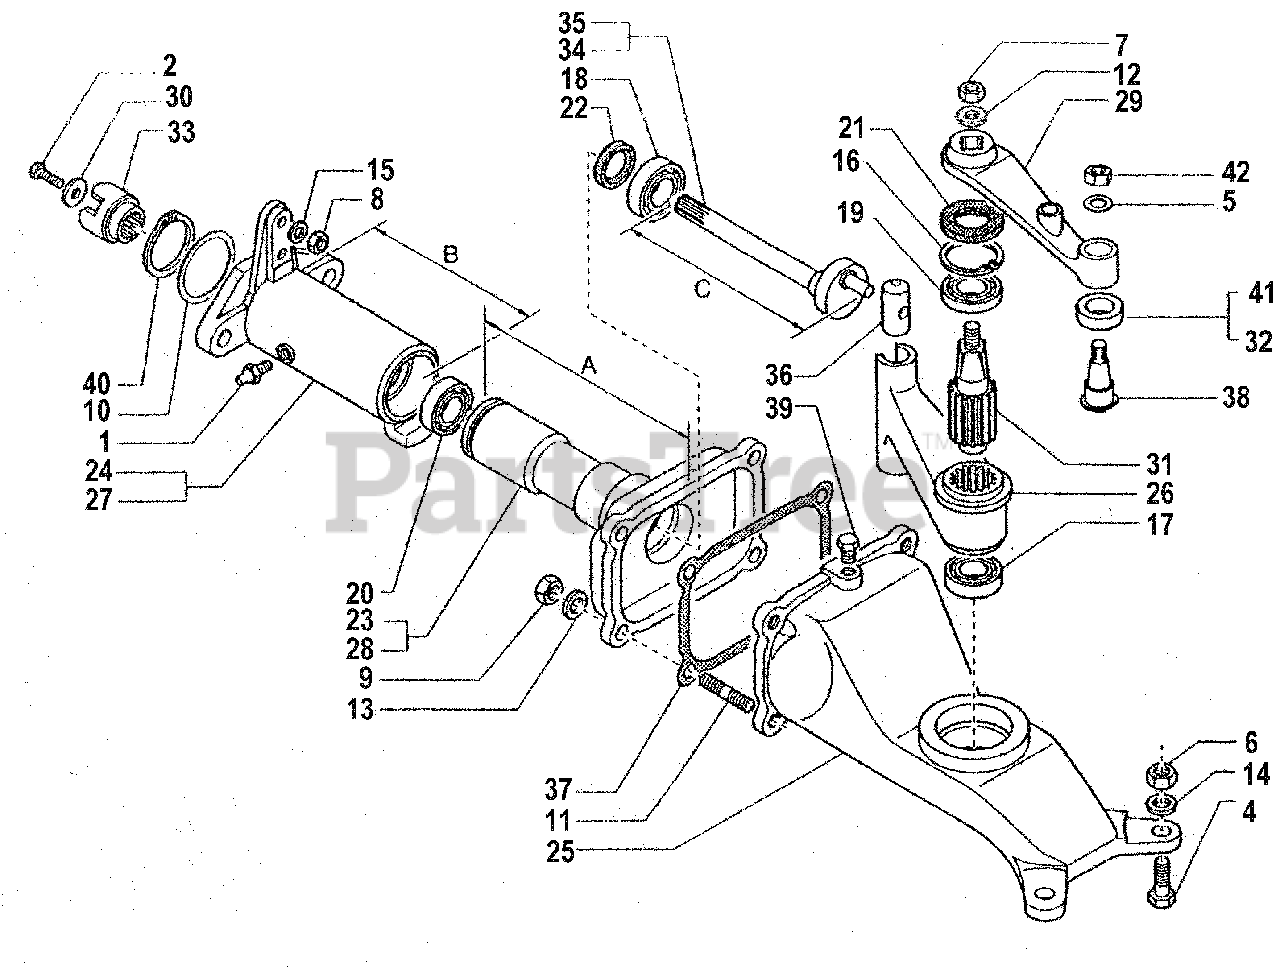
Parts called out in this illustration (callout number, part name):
1	LUBRICATOR, M10
2	SCREW, M6X16
3	SCREW M12X65
4	SCREW M14X40
5	SUPER WASHER, M10
8	NUT, SELF LOCKING, M8
9	NUT, SELF LOCKING, M10
10	SPACER RING
11	STUD, M10X50X22X14
13	SUPER WASHER, M10
14	SUPER WASHER, M14
15	WASHER, LOCK, M8.4
16	CIRCLIP, INTERNAL
17	BEARING, M15X42X13
18	BEARING, M25X62X17
19	BEARING, 35X62X14
20	BEARING, M20X42X12
21	OIL SEAL, 35X62X7
22	OIL SEAL, 25X52X7
23	BAR CONTROL SUPPORT, 10 1/2"
24	BAR CONTROL BUSHING, 7 11/16"
25	BLADE CONTROL BOX
26	CONTROL CRANK
27	BAR CONTROL BUSHING, 4 1/2" LONG
28	BAR CONTROL SUPPORT,7 3/8" LONG
29	CONNECTION ROD
30	3-DOG COUPLING
31	SHAFT, CONNECTION ROD
32	BLADE BUSHING D. 32
33	PTO COUPLING
34	CRANK CAM, 7" LONG
35	CRANK CAM, 10 3/16" LONG
39	BREATHER CAP
40	SNAP RING INTERNAL
41	BLADE BUSHING D. 37-1S
42	NUT M10 DEFORMED
